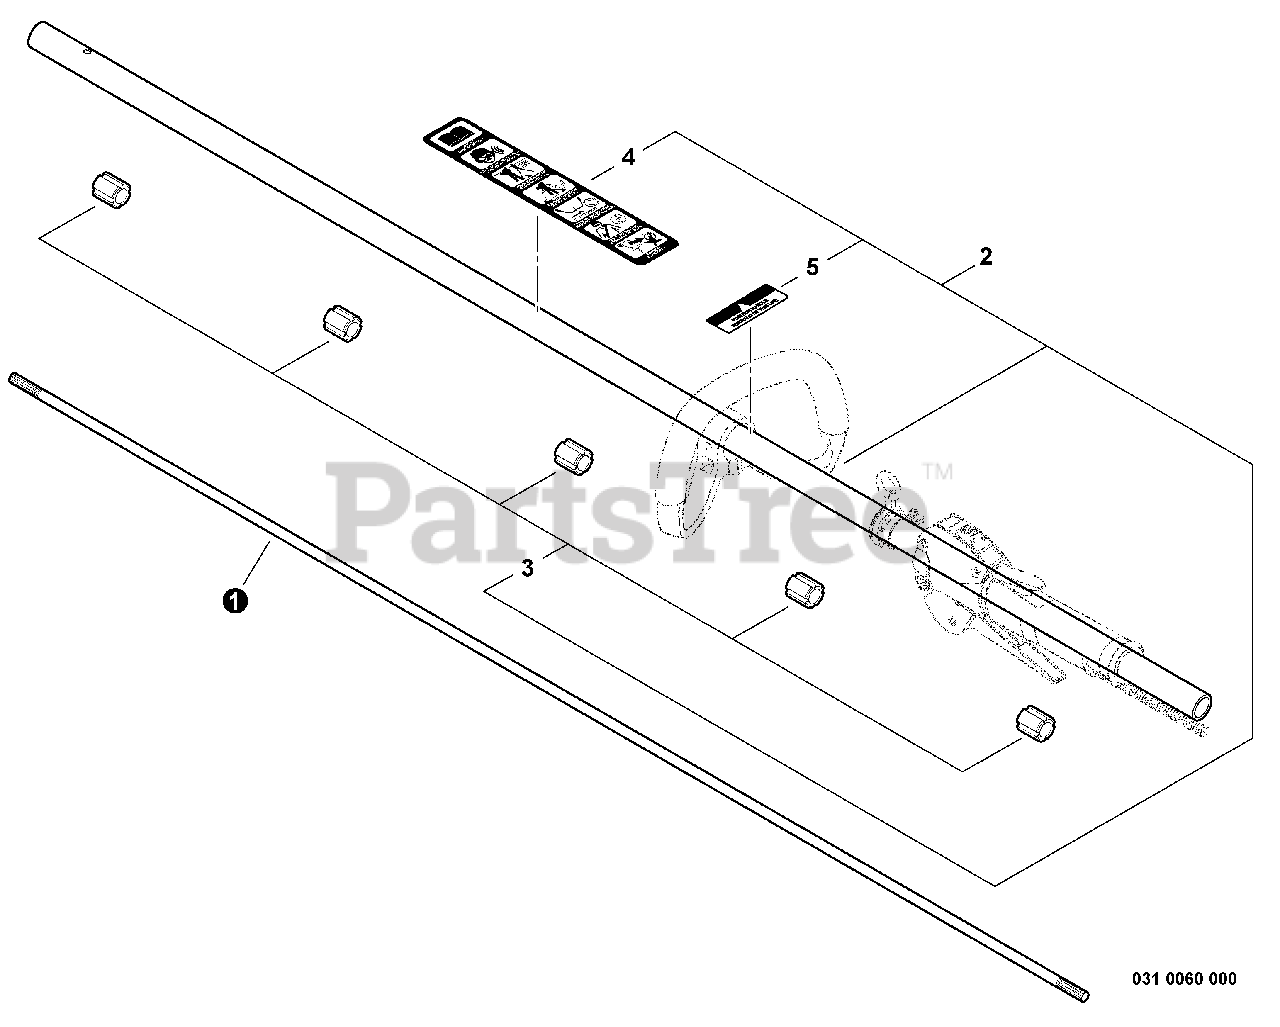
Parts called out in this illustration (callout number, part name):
1	DRIVESHAFT
2	MAIN PIPE ASSY
3	BUSHING
4	LABEL - CAUTION
5	LABEL - HANDLE LOCATION
